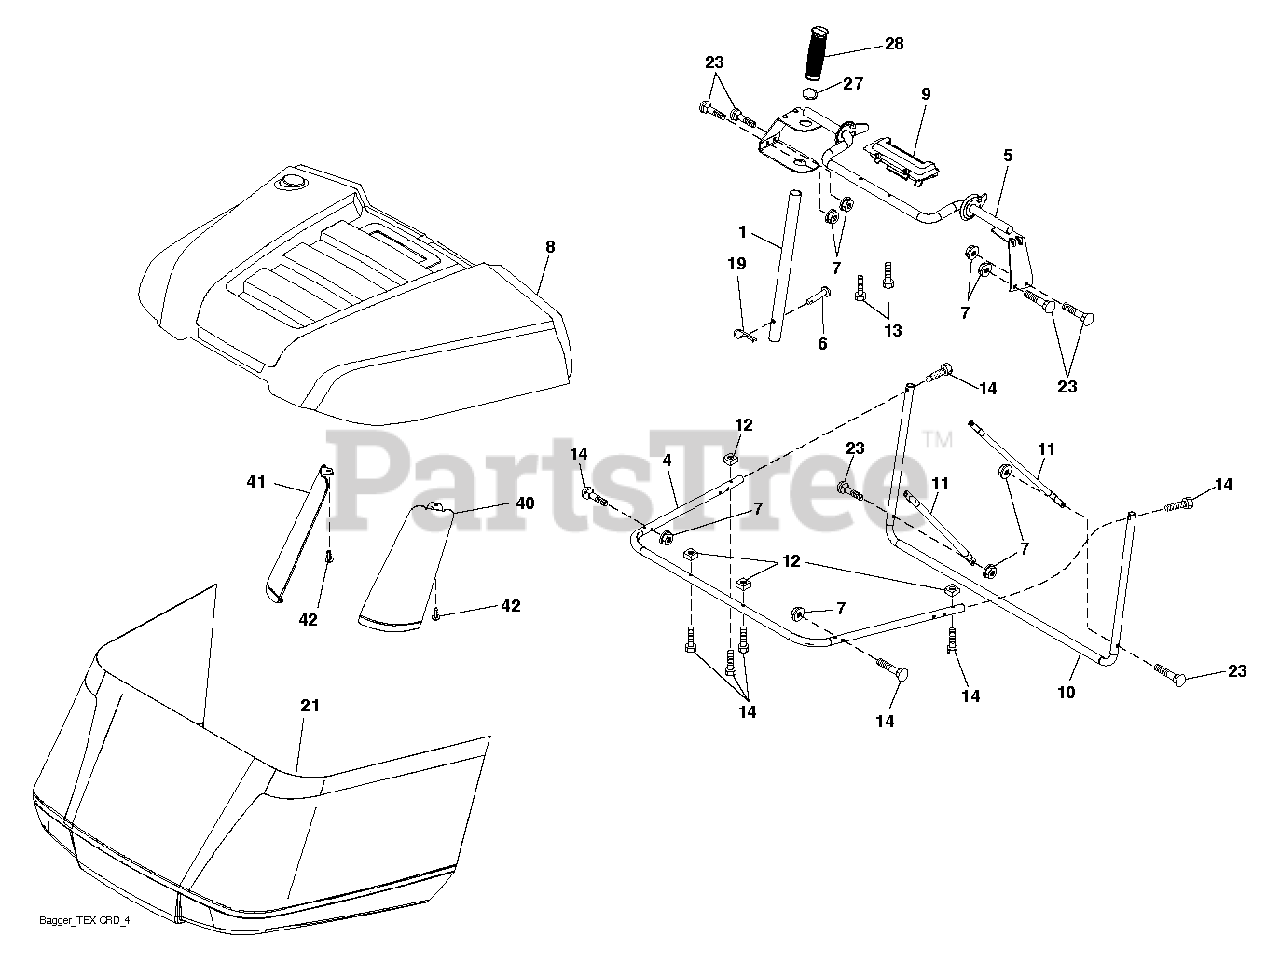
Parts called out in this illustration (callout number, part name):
1	TUBE.PNT.HDL.BAGGER.
6	RIVET,DRILLED
7	NUT T
19	PIN.COTTER.5/16.BOW TI
28	GRIP.HANDLE.BLACK
